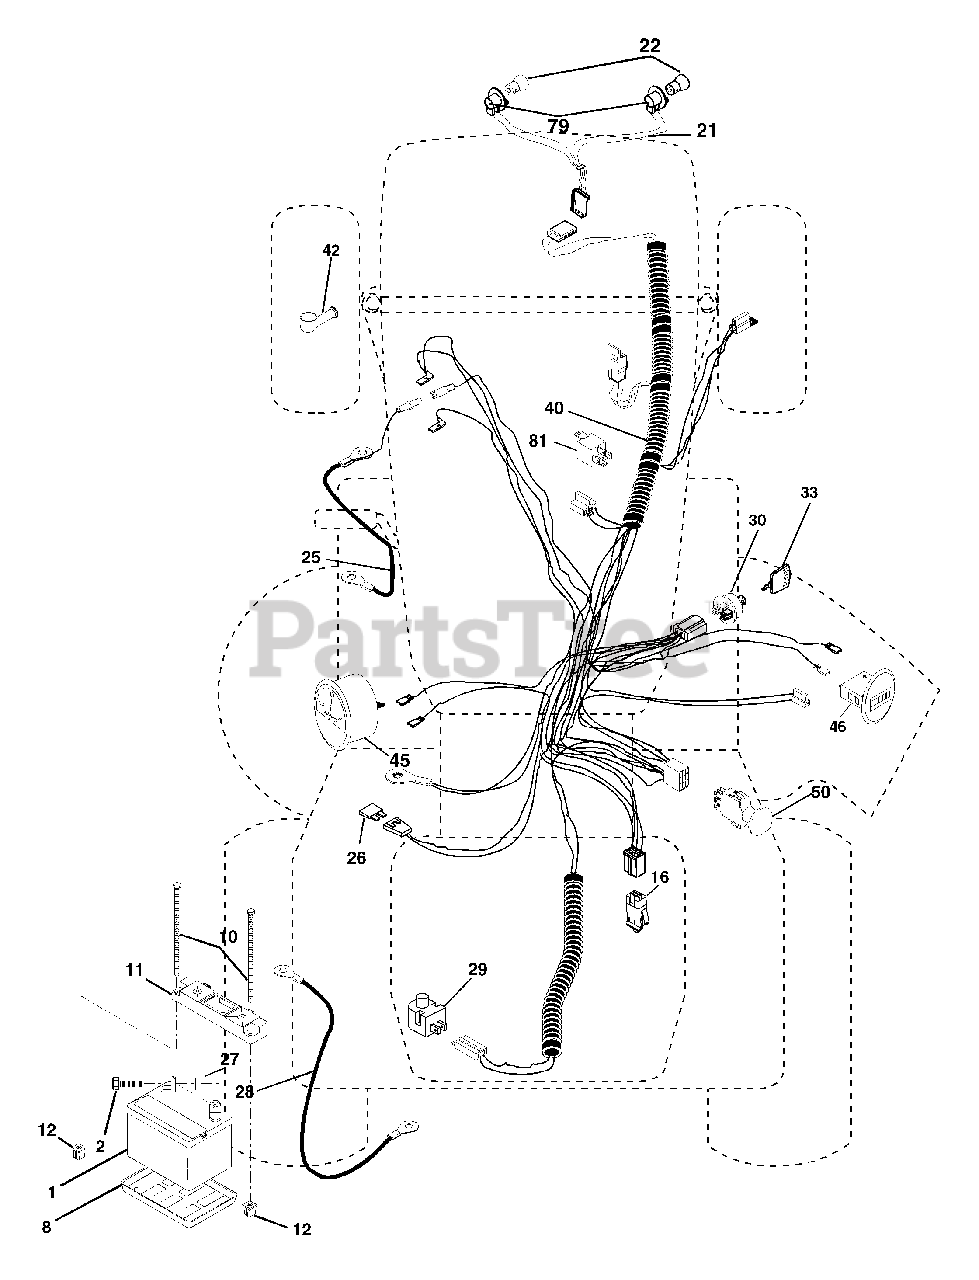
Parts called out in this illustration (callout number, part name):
1	Battery
2	Bolt Hex Head 1/4-20 x 3/4
8	Tray, Battery
10	Bolt, Battery Front 1/4-20 x 7.5 Zinc
11	Holddown Battery Front Mount
12	Nut, Push Nylon 1.4" Battery Front
16	Switch Interlock Push-In
21	Harness Socket Light w/4152J
22	Bulb Light
27	Nut Keps Hex 1/4-20
28	Cable Bolt Ground
29	Switch, Plunger NC Gray
30	Switch, Ign
40	Harness Ign.
42	Cover, Terminal Red
50	Switch, PTO
79	Bulbholder Asm
81	Relay Asm.
